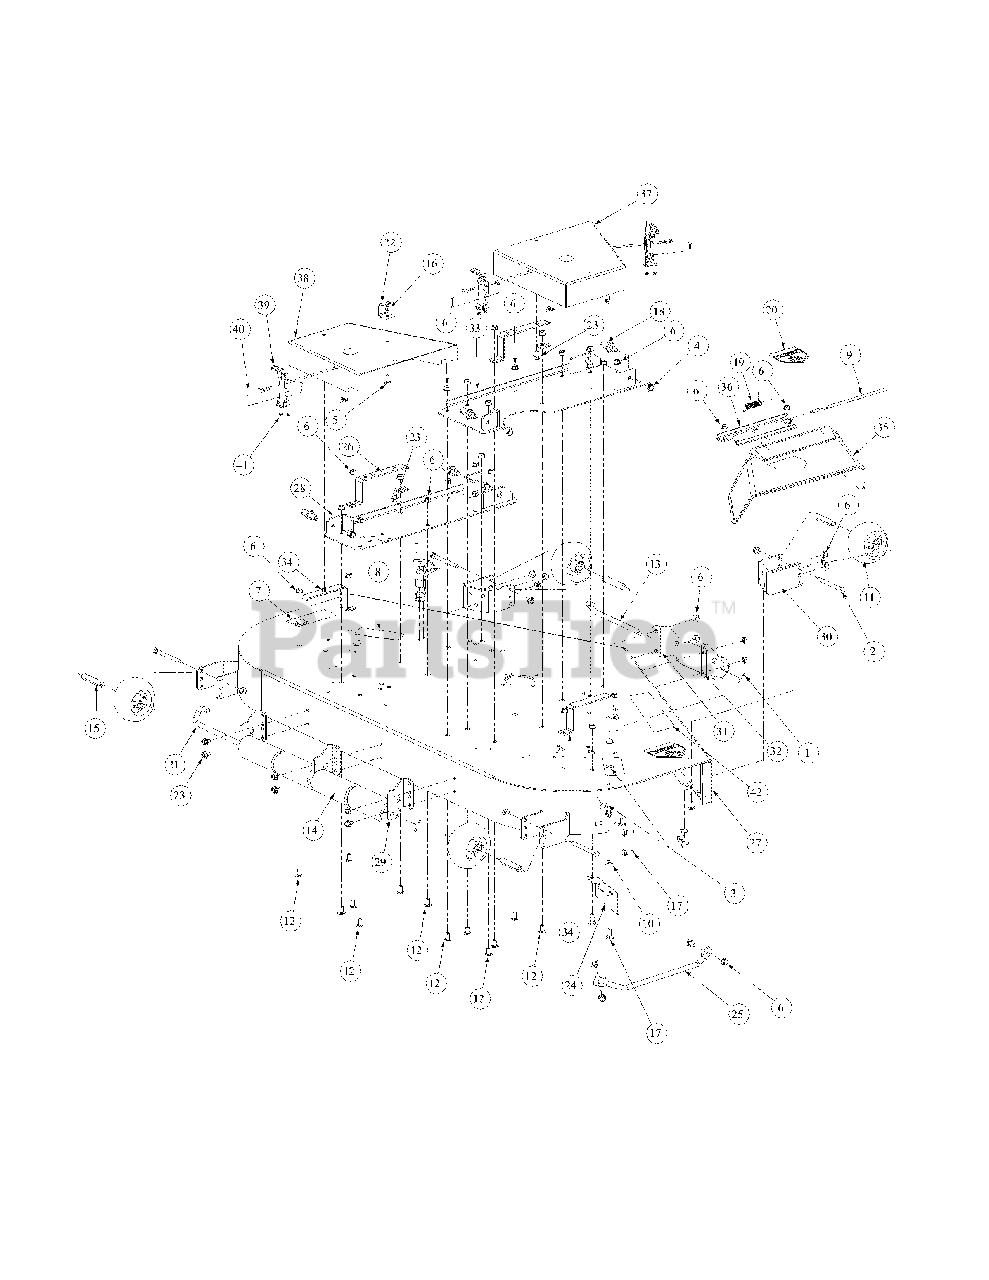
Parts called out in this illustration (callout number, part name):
1	Cotter Pin, .125 Dia. x 1.0
2	Hex Cap Screw, 3/8-16, 3.75
3	Flat Washer, 3/8
4	Lock Nut, Nylon Insert, 1/2-13
5	Hex Cap Screw, 5/16-18 x 3/4
6	Flange Lock Hex Nut, 3/8-16
7	Decal, Rotating Blade
8	Decal, Warning Shield Missing
9	Chute Deflector Rod
10	Idler Washer
11	Complete Wheel, 5.00 Dia.
12	Carriage Bolt, 3/8-16 x .75 Lg.
13	Roller Pin, 1/2 Dia. x 7.31 Lg.
14	Front Roller
15	Wheel Spacer
16	Hex Flange Lock Nut, 5/16-18
17	Carriage Bolt, 3/8-16 x 1
18	Pin, 5/8 Dia. x 1.2 Lg.
19	Torsion Spring, 0.4ID x 2.16Lg
20	Decal, Danger Hand and Feet
21	Roller Pin
22	Tension Rod Stop Bracket
23	Hex Index Washer Screw, 3/8-16, .5
24	Chute Bracket
25	Finger Guard
26	Belt Cover Support
27	60 Deck Assembly
28	Left Hand Mount Deck Bracket Assembly
29	Deck Roller Mount Bracket
30	Anti-Scalp Wheel Front Mount Bracket
33	Right Hand Deck Bracket Assembly
34	Outer Belt Cover Support Assembly
35	Chute Deflector
36	Chute Deflector Bracket
37	Right Hand Deck Belt Cover Weldment
38	Left Hand Deck Belt Cover Weldment
39	T-Handle Latch Draw
40	Phillips Head Screw, 10-32
41	Lock Nut, Nylon Insert, 10-32
42	Commercial Mower Label
